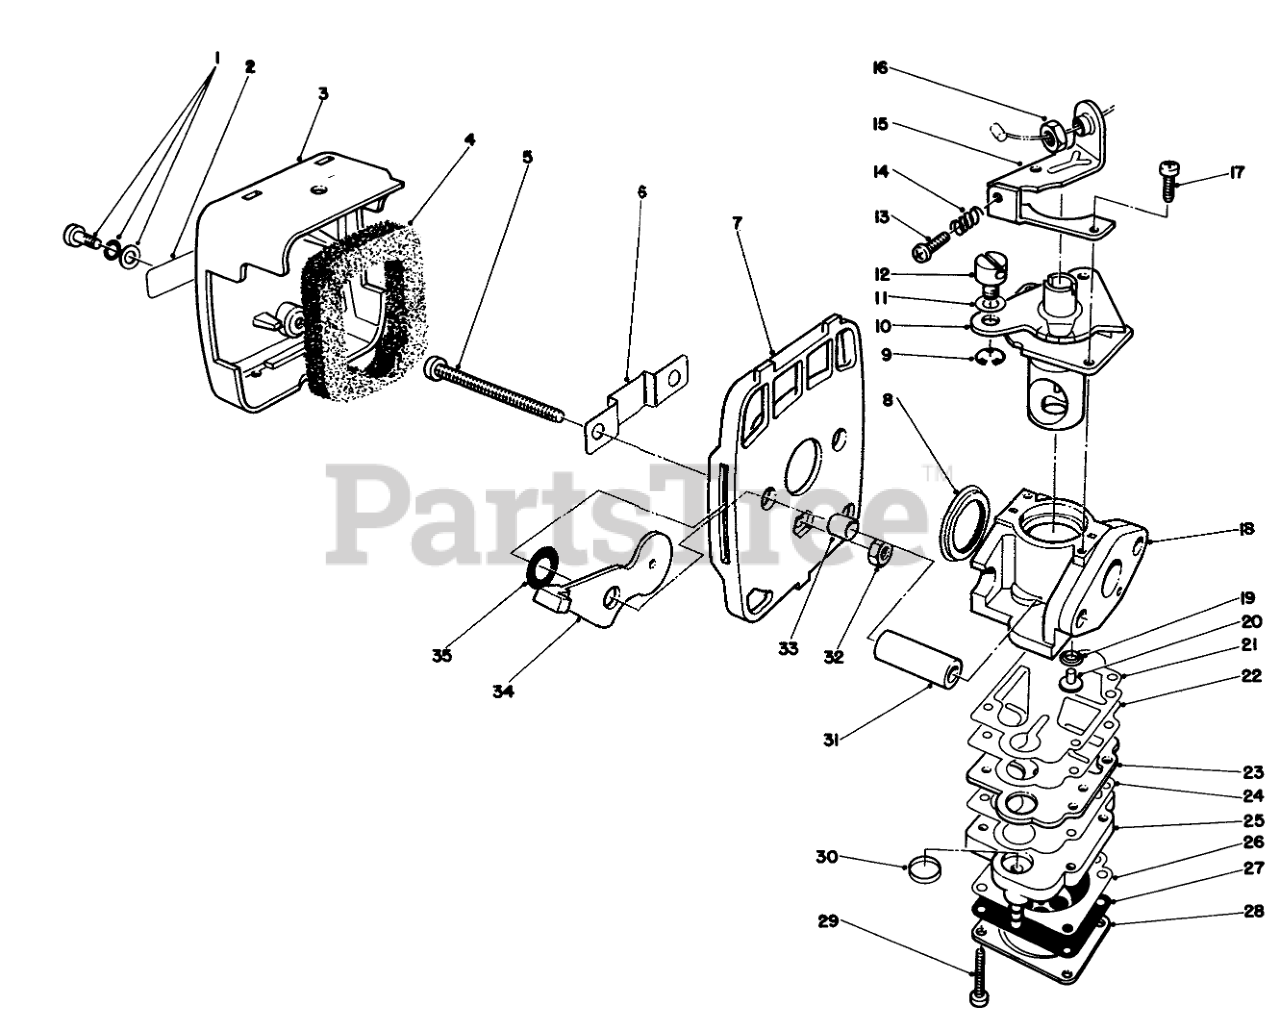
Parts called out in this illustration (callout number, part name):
1	SCREW ASSEMBLY
2	Decal-Choke
3	Cover Assembly (Incl. Ref. #2)
4	ELEMENT
5	SCREW
6	PREVENT PLATE
7	AIR CLEANER PLATE
8	RING PACKING
9	RING - SPRING RETAINER
10	VALVE ASSEMBLY
11	WASHER
12	SWIVEL
13	Screw-Idle Adjustment
14	SPRING
15	BRACKET
17	Screw
18	Carburetor Assembly (Incl.Ref. #8-15, 17 & 19-30)
19	O-RING
21	PUMP GASKET
22	Diaphragm-Pump
23	PUMP PLATE
24	Diaphragm-Pump
25	BODY ASSEMBLY
26	GASKET
27	Diaphragm Assembly
28	DIAPHRAGM COVER
29	SCREW
30	SCREEN INLET
31	SLEEVE
32	INSULATOR NUT
33	SPACER
34	CHOKE LEVER
35	RUBBER SEAT
